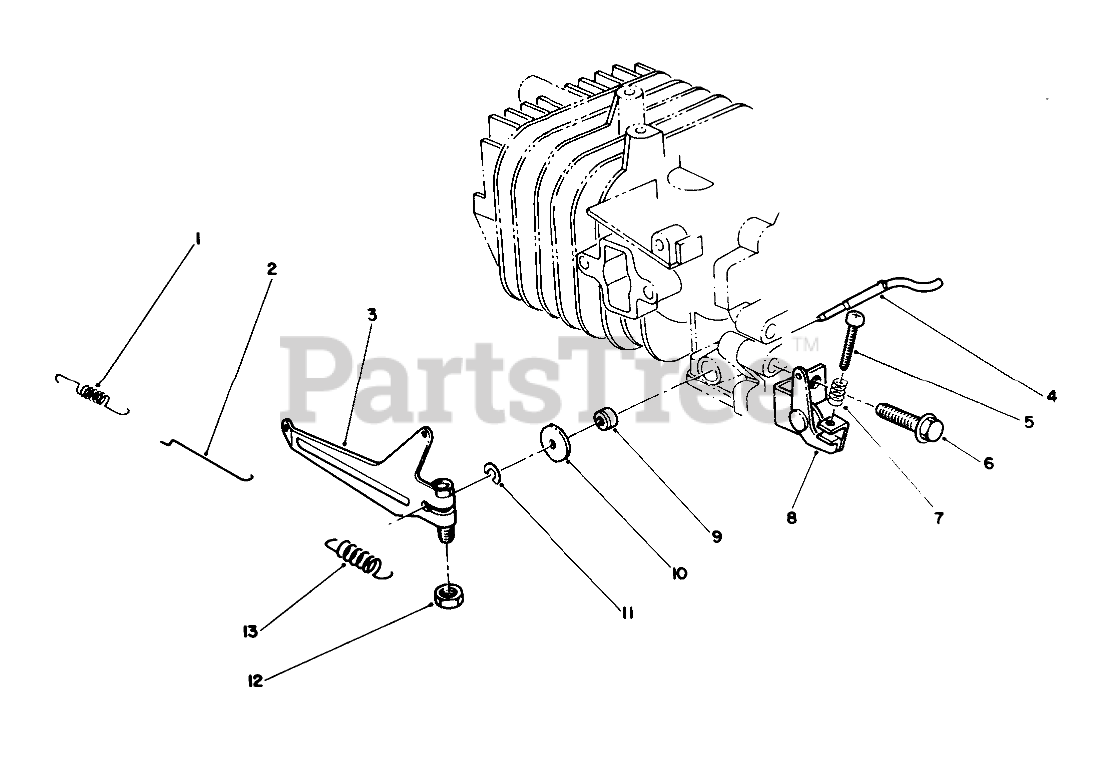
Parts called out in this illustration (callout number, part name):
1	CARB SPRING
2	CARB ROD
3	GOVERNOR ARM
4	SHAFT
5	SCREW
7	SPRING
8	GOV SPR BRKT
9	SEAL-OIL
10	WASHER
11	E-RING
13	GOV SPRING
